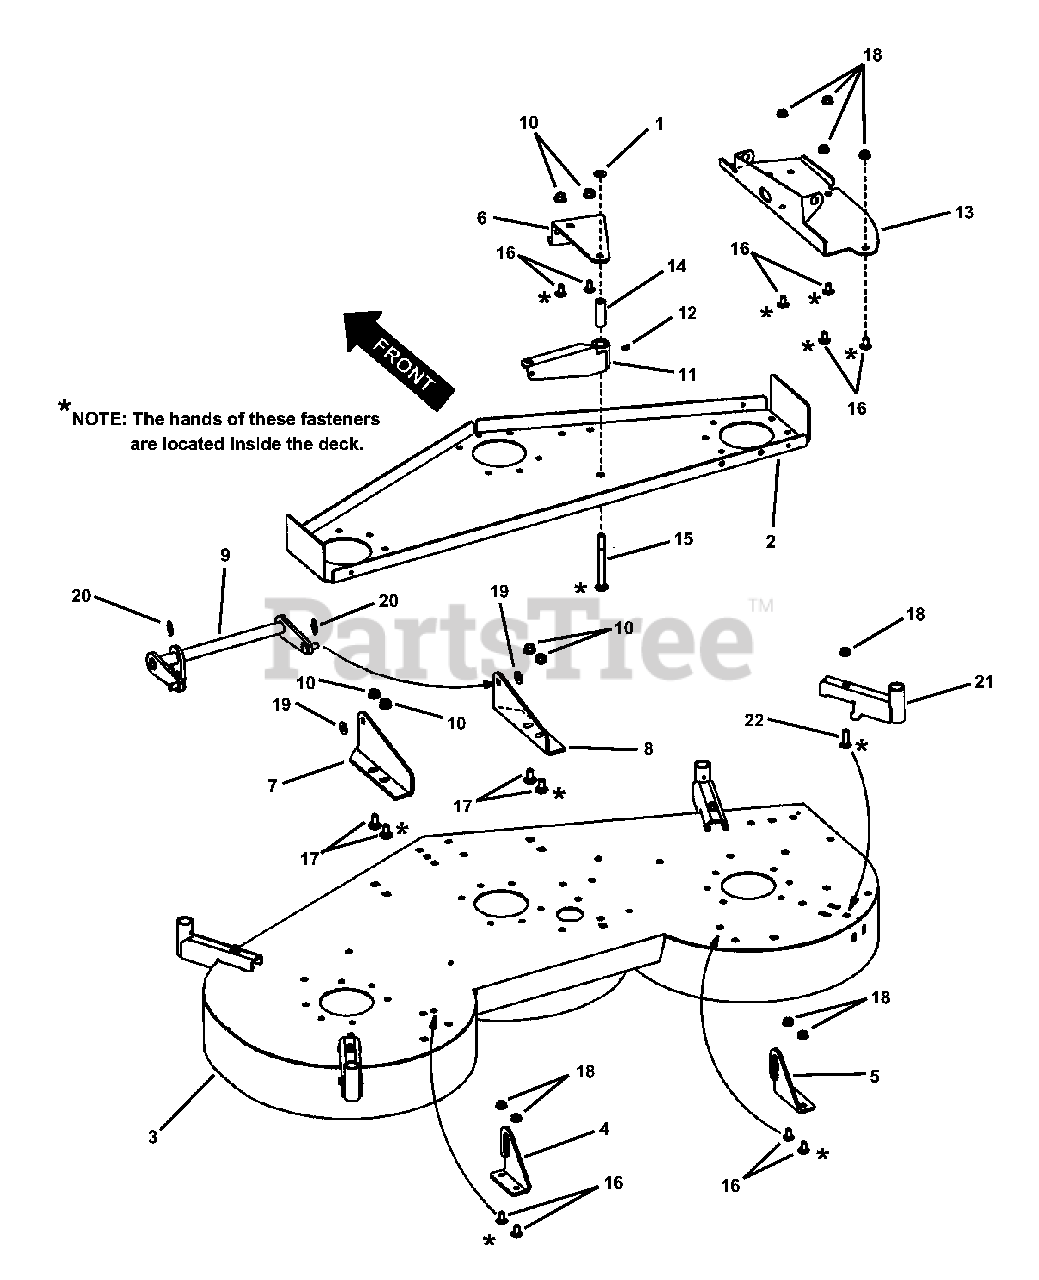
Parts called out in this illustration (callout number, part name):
1	RETAINER, 3/8" Bolt
2	STIFFENER, Deck
3	WELDMENT, 48" Deck
4	HANGER, R.H. Rear
5	HANGER, L.H. Rear
6	BRACKET, Pulley Mounting
7	BRACKET, L.H. Front Lift
8	BRACKET, R.H. Front Lift
9	WELDMENT, Front Lift Arm
10	NUT, 3/8-16 Hex Flange Lock
11	ASSEMBLY, Idler Arm/Lube Fitting
12	LUBE FITTING, Straight (press-fit for .187 dia. Hole)
13	BRACKET, Hinge (48" Deck)
14	SPACER, Pivot Collar
15	BOLT, 3/8-16 x 4" Square Neck Carriage, Grade 5
16	BOLT, 5/16-18 x 5/8" Short Neck Carriage, Grade 5
17	BOLT, 3/8-16 x 1" Short Neck Carriage, Grade 5
18	NUT, 5/16-18 Hex Flange Lock, Grade 5
19	WASHER, 3/8" Flat
20	PIN, 3/64 x 1-7/32" Locking Cotter
21	WELDMENT, Caster
22	BOLT, 5/16-18 x 1-1/8" Short Neck Carriage, Grade 5
